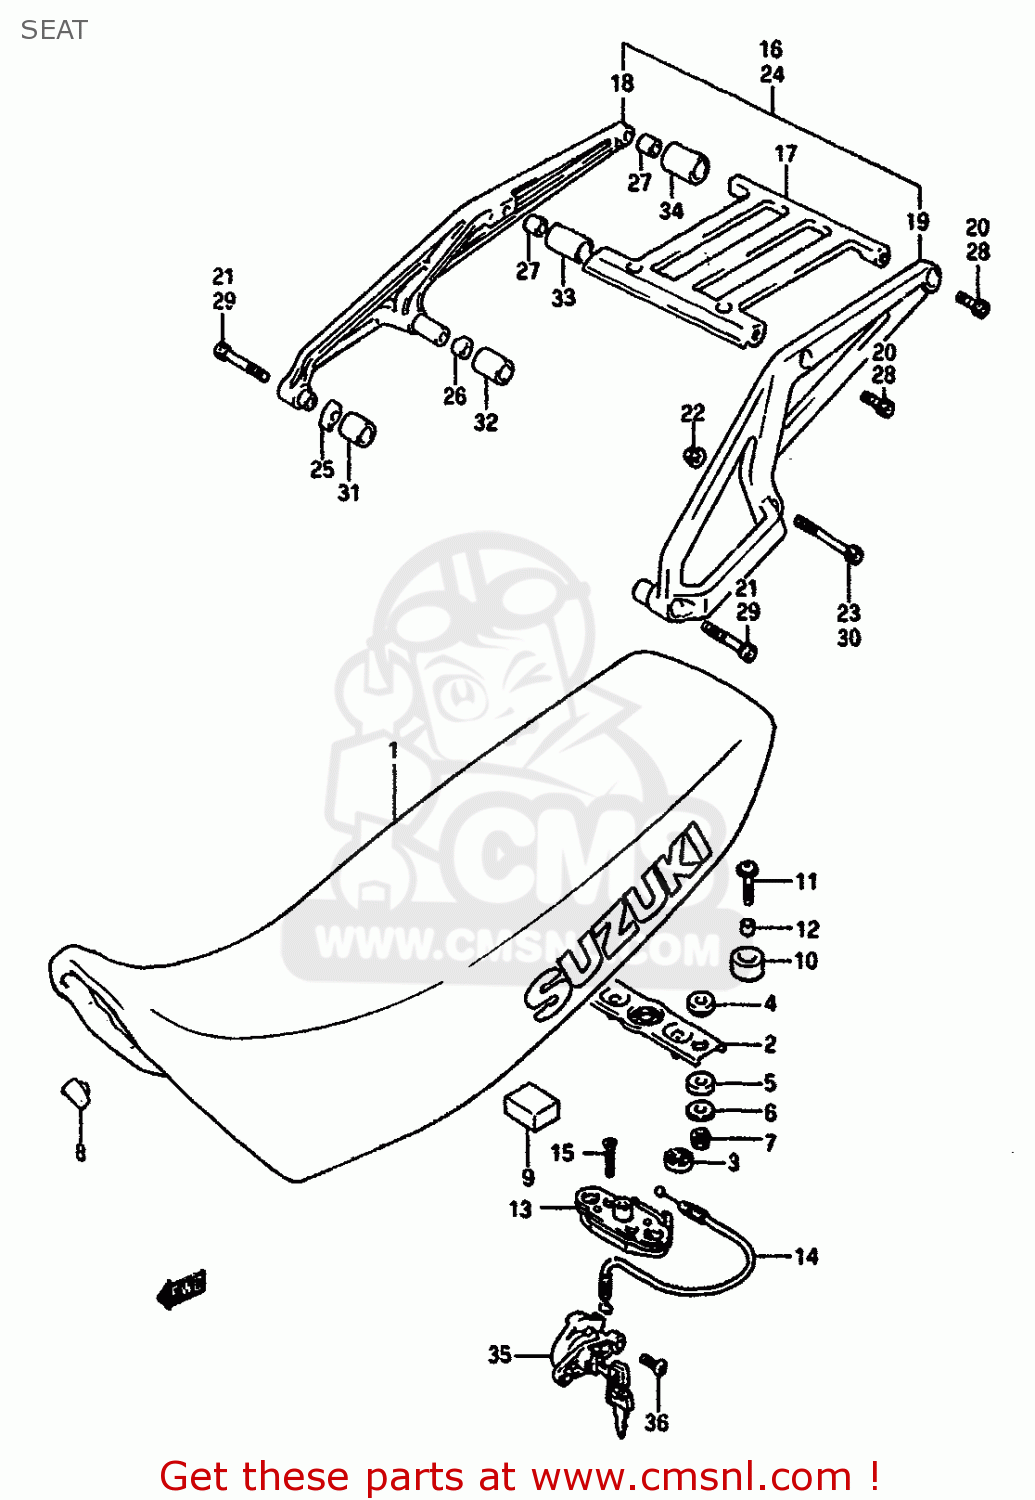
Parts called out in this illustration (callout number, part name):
1	SEAT SET
2	STRIKER,SEAT LOCK
3	CUSHION,SEAT LOCK(10X22X6)
4	CUSHION,UPR
5	CUSHION,LWR
6	WASHER
7	NUT
8	CUSHION
9	CUSHION,TOOL(40X30X15)
10	CUSHION,COVER
11	SCREW
12	SPACER (6.1X8X8)
13	BRACKET,SEAT SUPPORT,RIGHT
14	CABLE,SEAT LOCK
15	SCREW
16	CARRIER,REAR (SILVER)
17	REAR CARRIER,CENTER (SILVER)
18	REAR CARRIER,RH (SILVER)
19	REAR CARRIER,LH (SILVER)
20	BOLT
21	BOLT(8X50)
22	NUT
23	BOLT
24	CARRIER ASSY,REAR (SILVER)
25	SPACER,FRONT (SILVER)
26	SPACER,CENTER (SILVER)
27	SPACER,REAR (SILVER)
28	BOLT,UPPER
29	BOLT,REAR
30	BOLT,CENTER
31	CUSHION,FRONT RH
32	CUSHION,NO.2
33	CUSHION,NO.3
34	CUSHION,NO.4
35	LOCK SET,HELMET
36	SCREW
